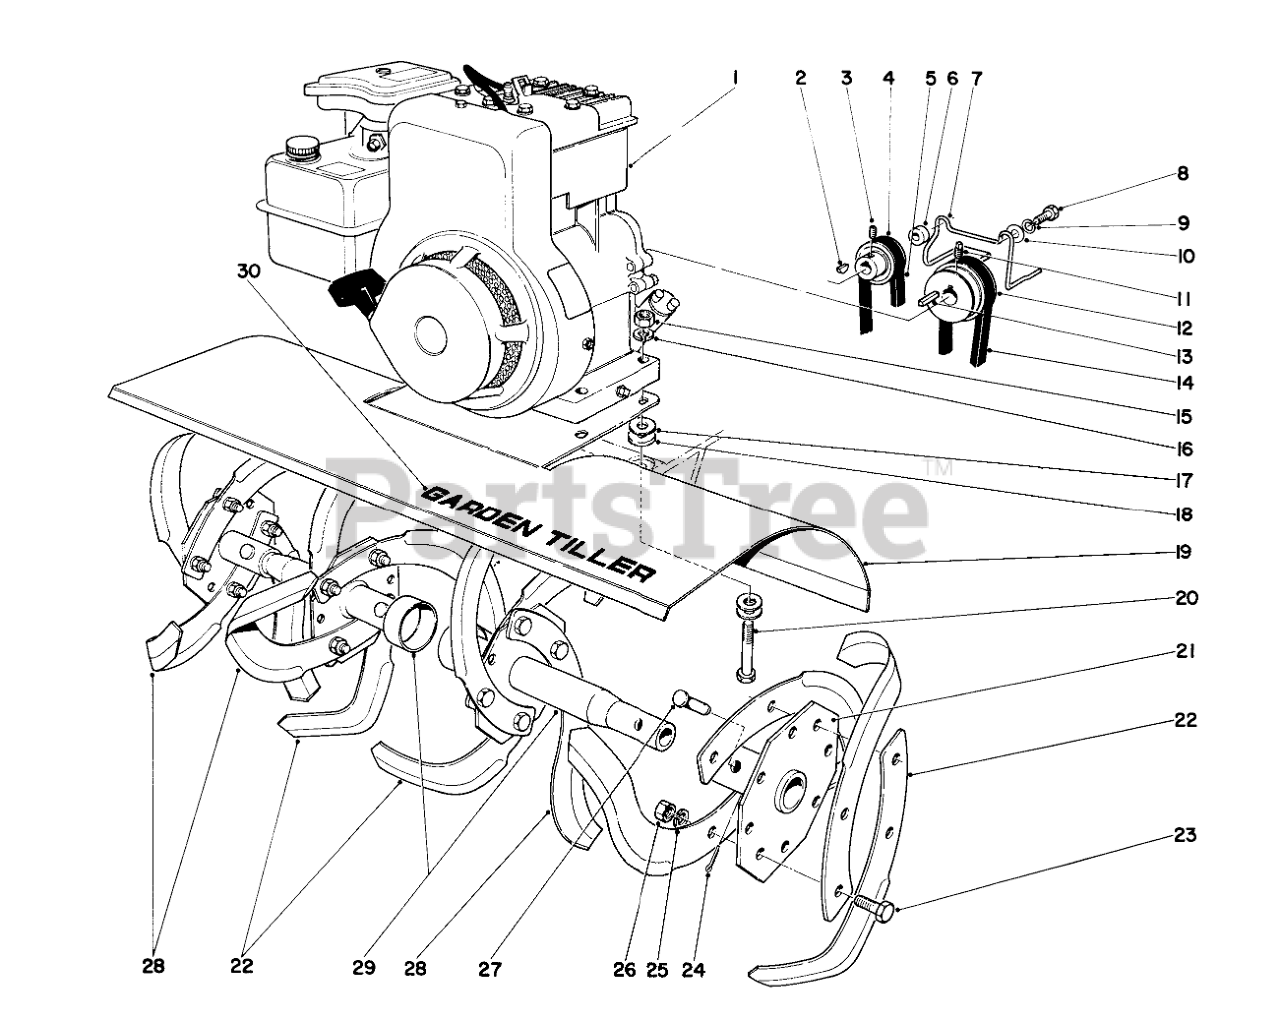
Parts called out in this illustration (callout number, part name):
1	Engine
2	KEY-WOODRUFF
3	SCREW-SET
4	Pulley
5	V-BELT
6	SPACER
7	BELT GUIDE
8	SCREW-HH
9	WASHER-LOCK
10	WASHER-FLAT
11	SCREW-SET, HSH
12	Engine Pulley
13	KEY-SQUARE
14	Belt
15	NUT-HEX
16	WASHER-LOCK
17	WASHER-FLAT
18	WASHER-FLAT
19	Shield
20	SCREW-HH
21	Axle Hub
22	RH TINE
23	SCREW-HH
24	PIN-COTTER
25	WASHER-LOCK
26	NUT-HEX
27	PIN-CLEVIS
28	LH TINE
29	Axle Hub
30	Decal
